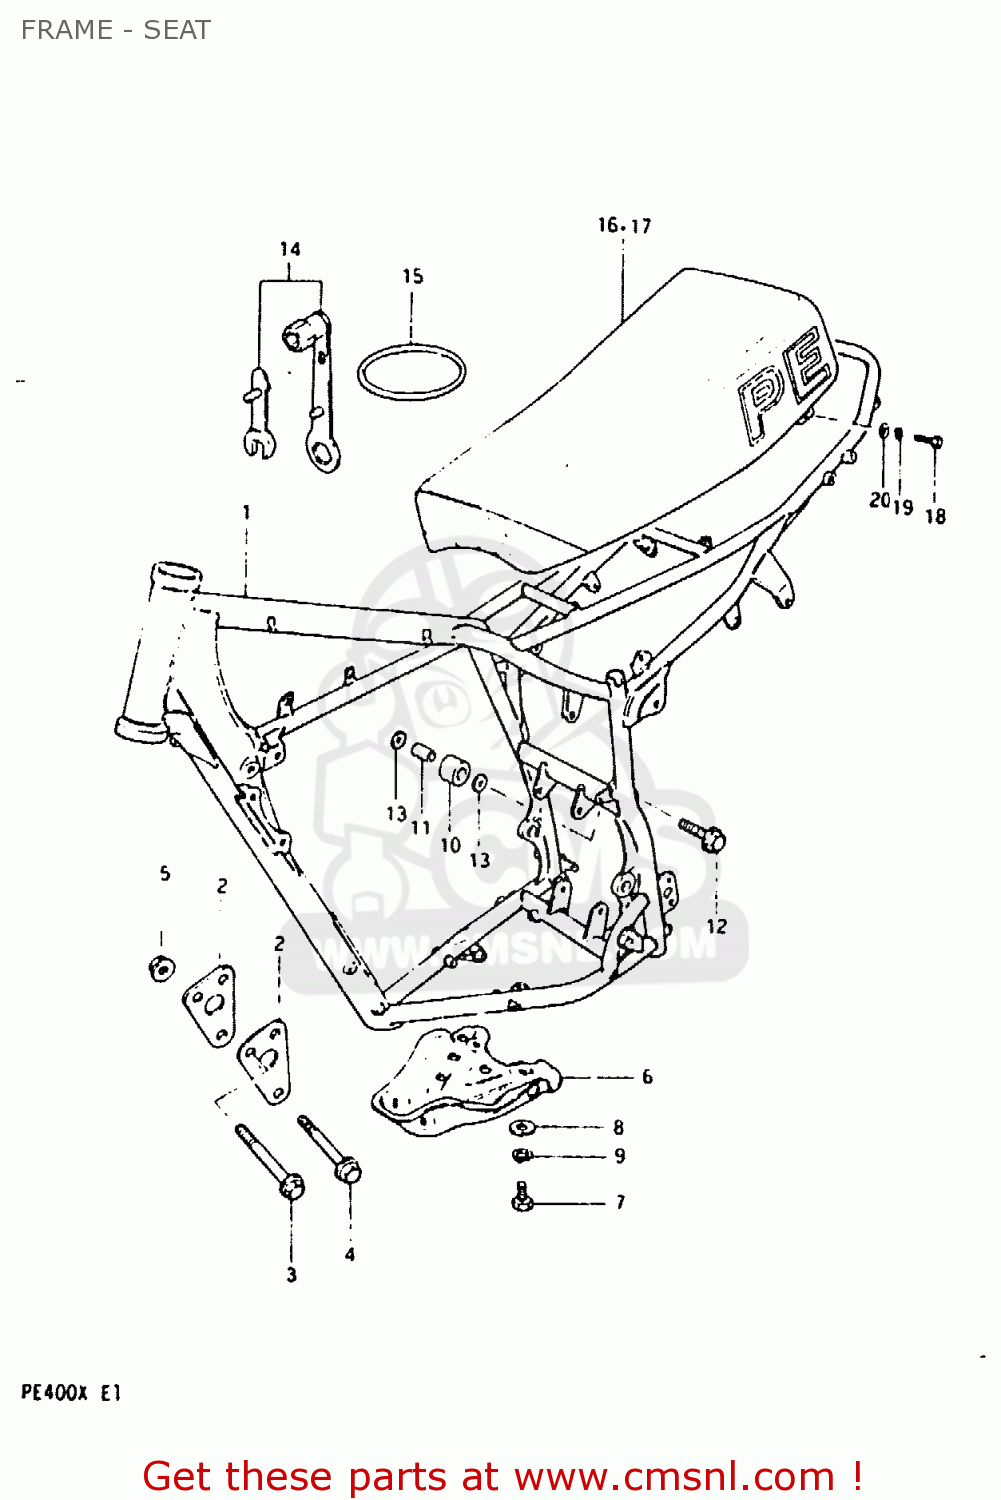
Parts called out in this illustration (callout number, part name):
1	FRAME (BLACK)
2	PLATE,ENGINE MOUNTING
3	BOLT(8X67)
4	BOLT
5	NUT
6	PROTECTOR,ENGINE
7	BOLT
8	WASHER (8.2X20X1.6)
9	LOCK WASHER
10	ROLLER,CHAIN CONTROL
11	SPACER,CHAIN LENGTH ROLLER
12	BOLT(8X45)
13	WASHER
14	SPARK PLUG WRENCH
15	O RING TOOL FITTING
17	SEAT ASSY (BLACK)
18	BOLT
19	LOCK WASHER
20	WASHER (8.2X20X1.6)
